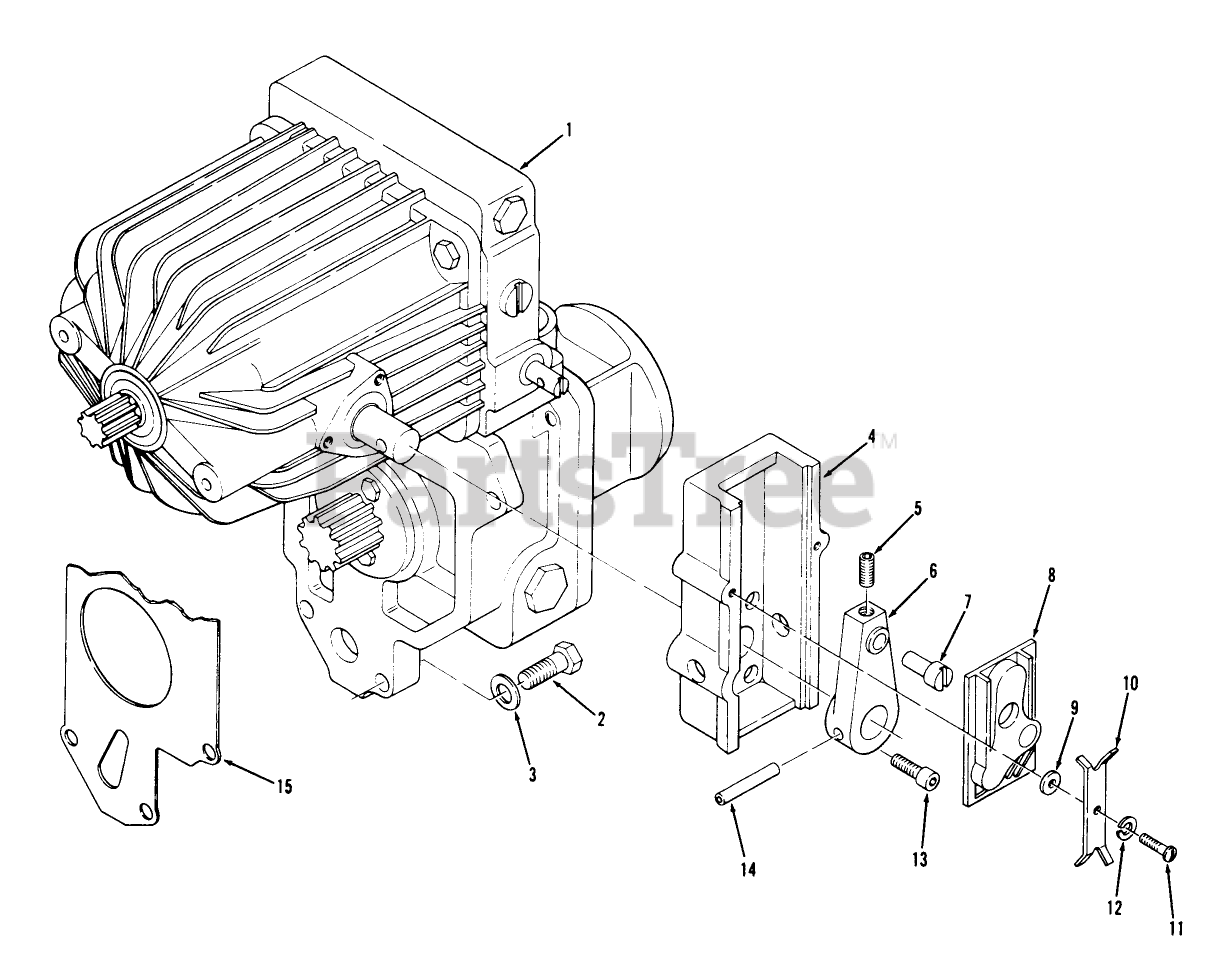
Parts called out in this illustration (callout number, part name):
1	SRV.BULLT 437B
1	SRV BULLT 437B
8	CAM
15	GASKET
